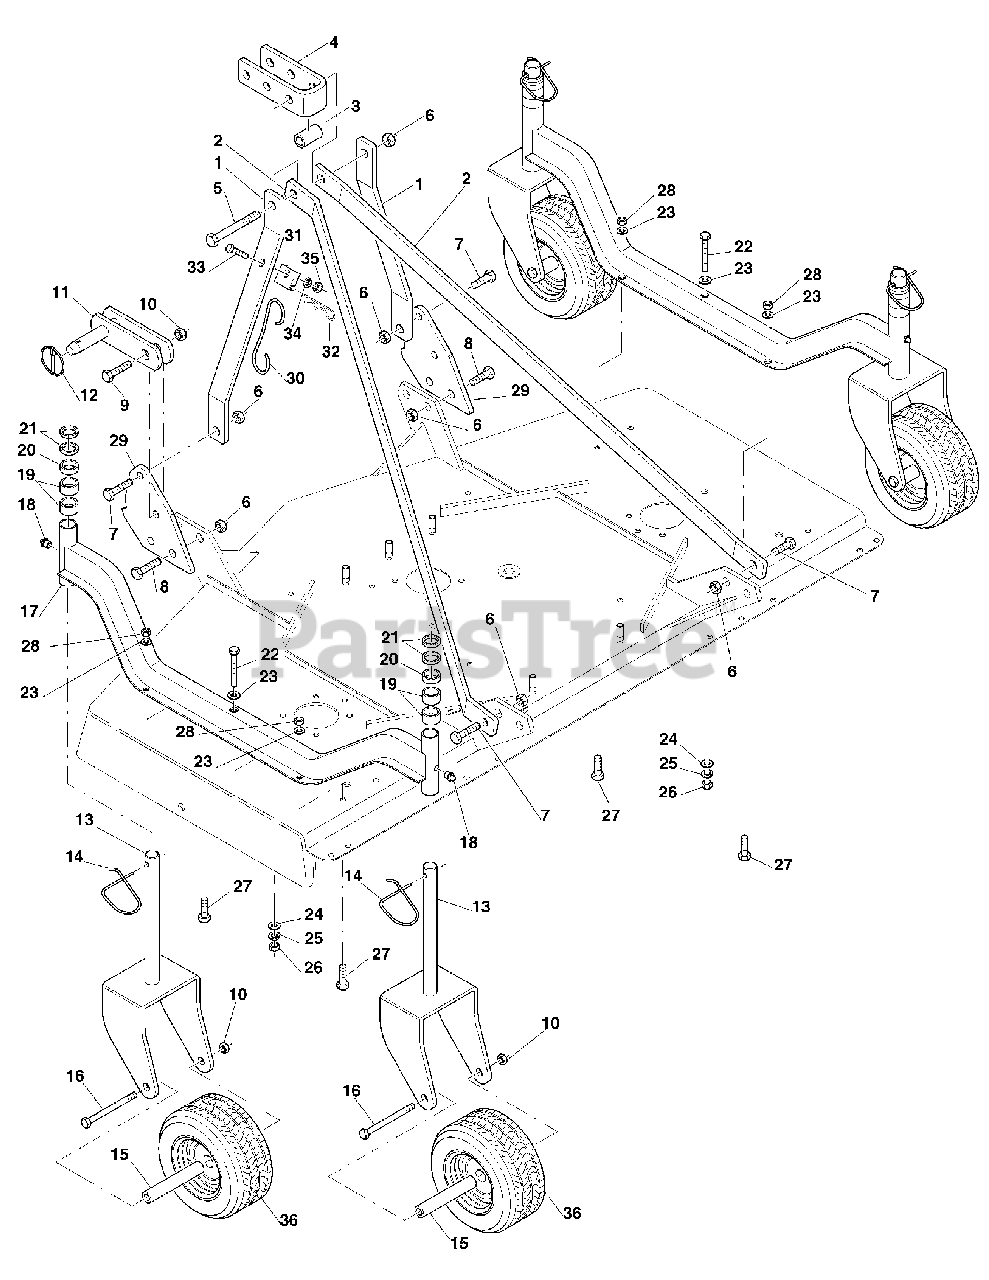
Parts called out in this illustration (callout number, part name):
1	Top Hitch Support
2	Top Hitch Arm 48''
2	Top Hitch Arm 60''
2	Top Hitch Arm 72''
3	Spacer
4	Upper Plate
5	Bolt TE 16 x 140
7	Bolt TE 16 x 40
8	Bolt TE 16 x 45
9	Bolt TE 14 x 45
11	Hitch Block
14	Cotter Pin
16	Bolt TE 14 x 140
17	Wheel Arm 48''
17	Wheel Arm 60''
17	Wheel Arm 72''
18	Grease Fitting
20	Spacer 1/2''
21	Spacer 1/4''
22	Bolt TE 10 x 90
23	Flat Washer D. 10
24	Flat Washer D. 10
25	Spring Washer D. 10
27	Bolt TE 10 x 30
29	Linking Plate
30	Driveline Hook
31	Hook Support
32	Cotter Pin D.2
33	Bolt TE 8 x 25
34	Spring Washer D.8
